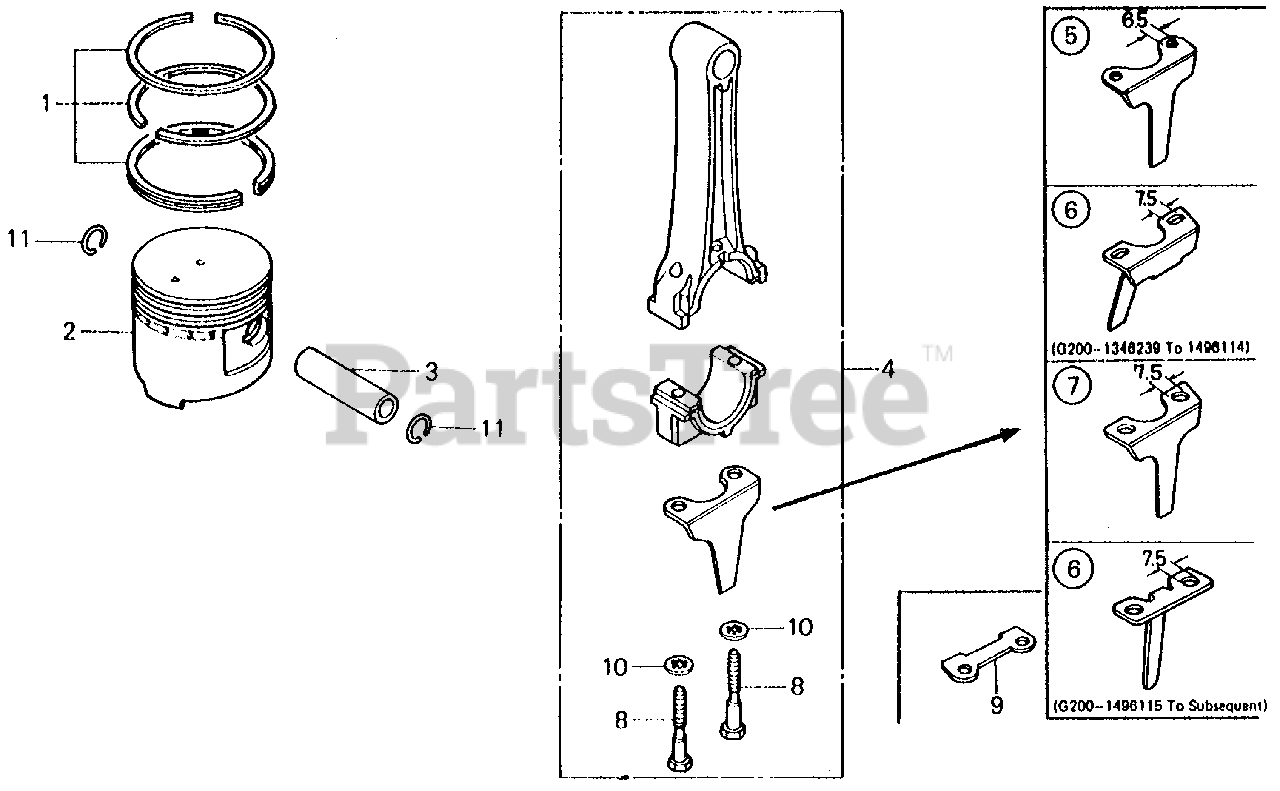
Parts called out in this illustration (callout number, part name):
1	RING SET, PISTON (STD)
1	RING SET, PISTON (OS 0.25)
1	RING SET, PISTON (OS 0.25) Use from Engine SN 1479289.
1	RING SET, PISTON (OS 0.50)
1	RING SET, PISTON (OS 0.50) Use from Engine SN 1479289.
1	RING SET, PISTON (OS 0.50) Use up to Engine SN 1152170.
1	RING SET, PISTON (OS 0.50) Use from Engine SN 1152171.
1	RING SET, PISTON (0.75)
1	RING SET, PISTON (0.75) Use from Engine SN 1479289.
2	PISTON (STD)
2	PISTON (OS 0.25)
2	PISTON (OS 0.50)
2	PISTON (0.75)
3	PIN, PISTON
4	ROD ASSY., CONNECTING
5	DIPPER, CONNECTING ROD
5	DIPPER, CONNECTING ROD (NOT AVAILABLE)
6	DIPPER, CONNECTING ROD
7	DIPPER, CONNECTING ROD (NOT AVAILABLE)
8	BOLT, CONNECTING ROD (6MM)
8	BOLT, CONNECTING ROD (6MM) (NOT AVAILABLE)
8	BOLT, CONNECTING ROD (7MM)
9	WASHER B, CONNECTING ROD
10	WASHER, LOCK (6MM) (N/A: SEE ASSEMBLY)
10	WASHER, LOCK (7MM)
11	CLIP, PISTON PIN (15MM)
